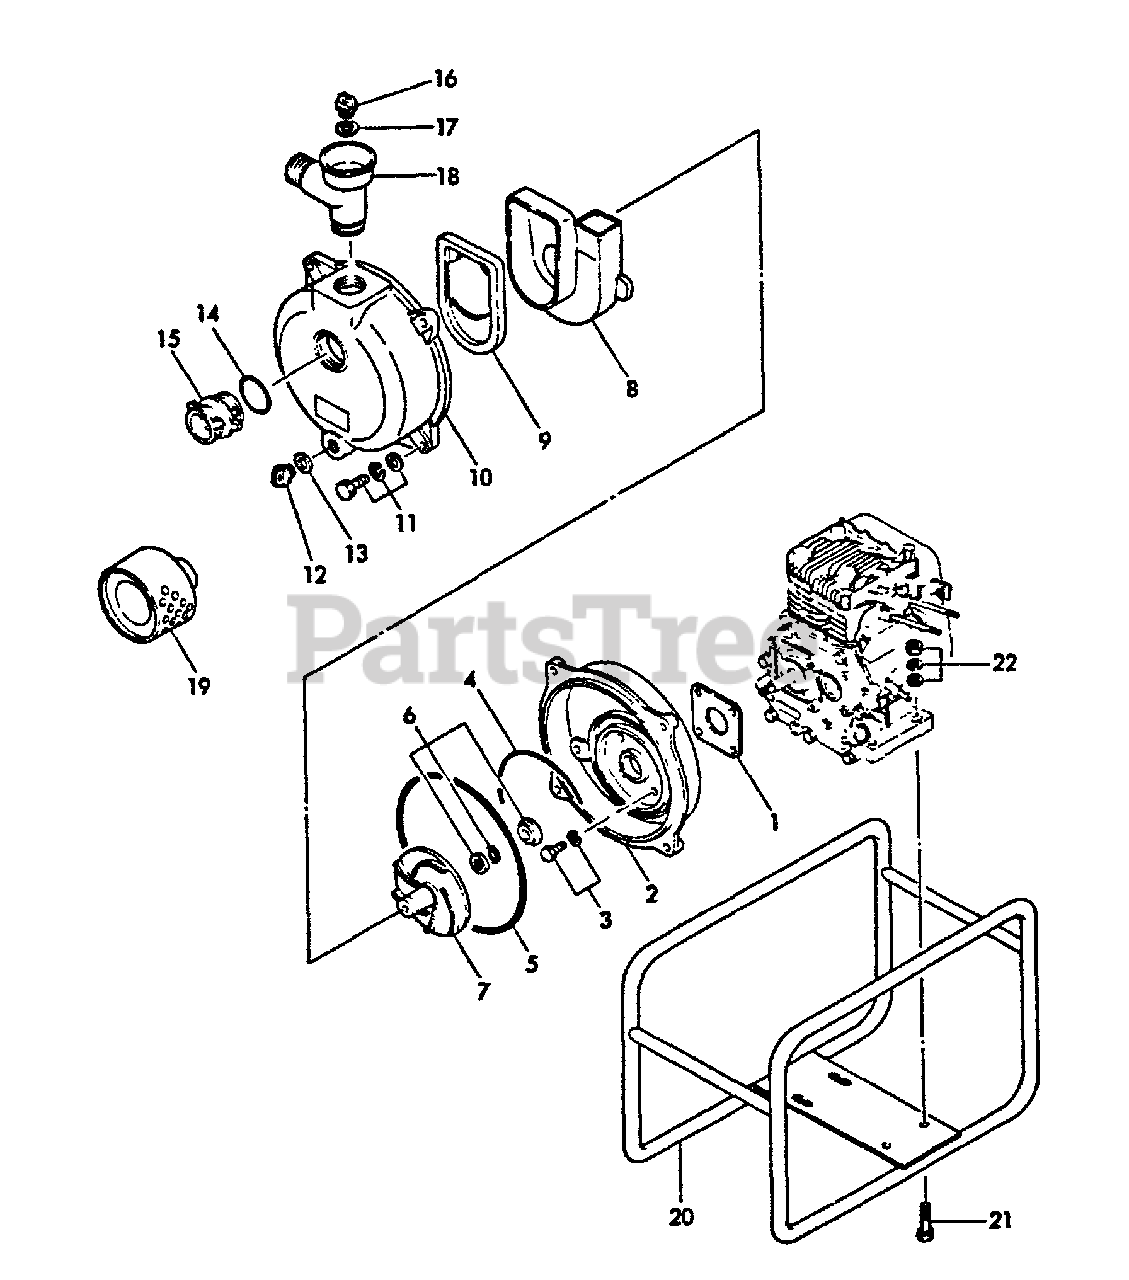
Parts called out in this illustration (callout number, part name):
1	GASKET, CASING
2	CASE, PUMP
3	BOLT, CASING
4	GASKET, CASING
5	O-RING, CASING
6	SEAL
7	IMPELLER
8	HOUSING
9	VALVE, STOP
10	COVER
11	BOLT, COVER
12	CAP, DRAIN
14	O-RING, HOSE NIPPLE
15	NIPPLE
16	CAP, DELIVERY
17	GASKET, DELIVERY
18	BEND, DELIVERY
19	STRAINER, DEBRIS
20	BASE
21	BOLT, ENGINE
22	NUT
